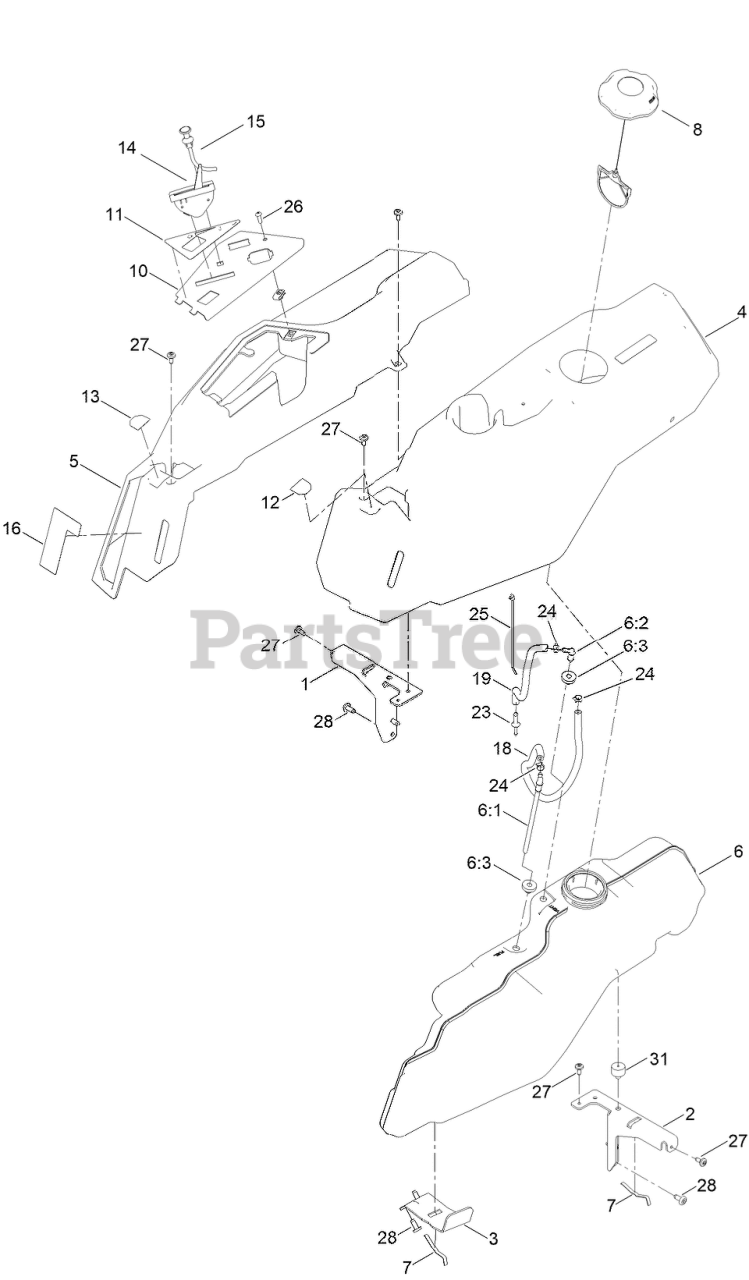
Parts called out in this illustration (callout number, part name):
1	SUPPORT-POD, RH
2	SUPPORT-POD, LH
3	SUPPORT-TANK, FUEL
4	POD-LH
5	POD-RH
6	FUEL TANK ASM
6:1	CONNECTOR-ELBOW, 90 DEG
6:2	FITTING-PLASTIC
6:3	BUSHING
7	SPRING
8	CAP-FUEL, RATCHETING
10	PANEL - CONTROL
11	DECAL-PANEL CONTROL
12	DECAL-CONTROL LEVER, LH
13	DECAL-CONTROL LEVER, RH
14	CABLE-THROTTLE
15	CABLE-CHOKE
16	DECAL-SMART SPEED
18	HOSE-FUEL
19	HOSE-FUEL
23	ADAPTOR-ORIFICE
24	CLAMP-HOSE
25	TIE-CABLE
26	SCREW-PRH
27	SCREW-SHOULDER
31	BUMPER-GROMMET
